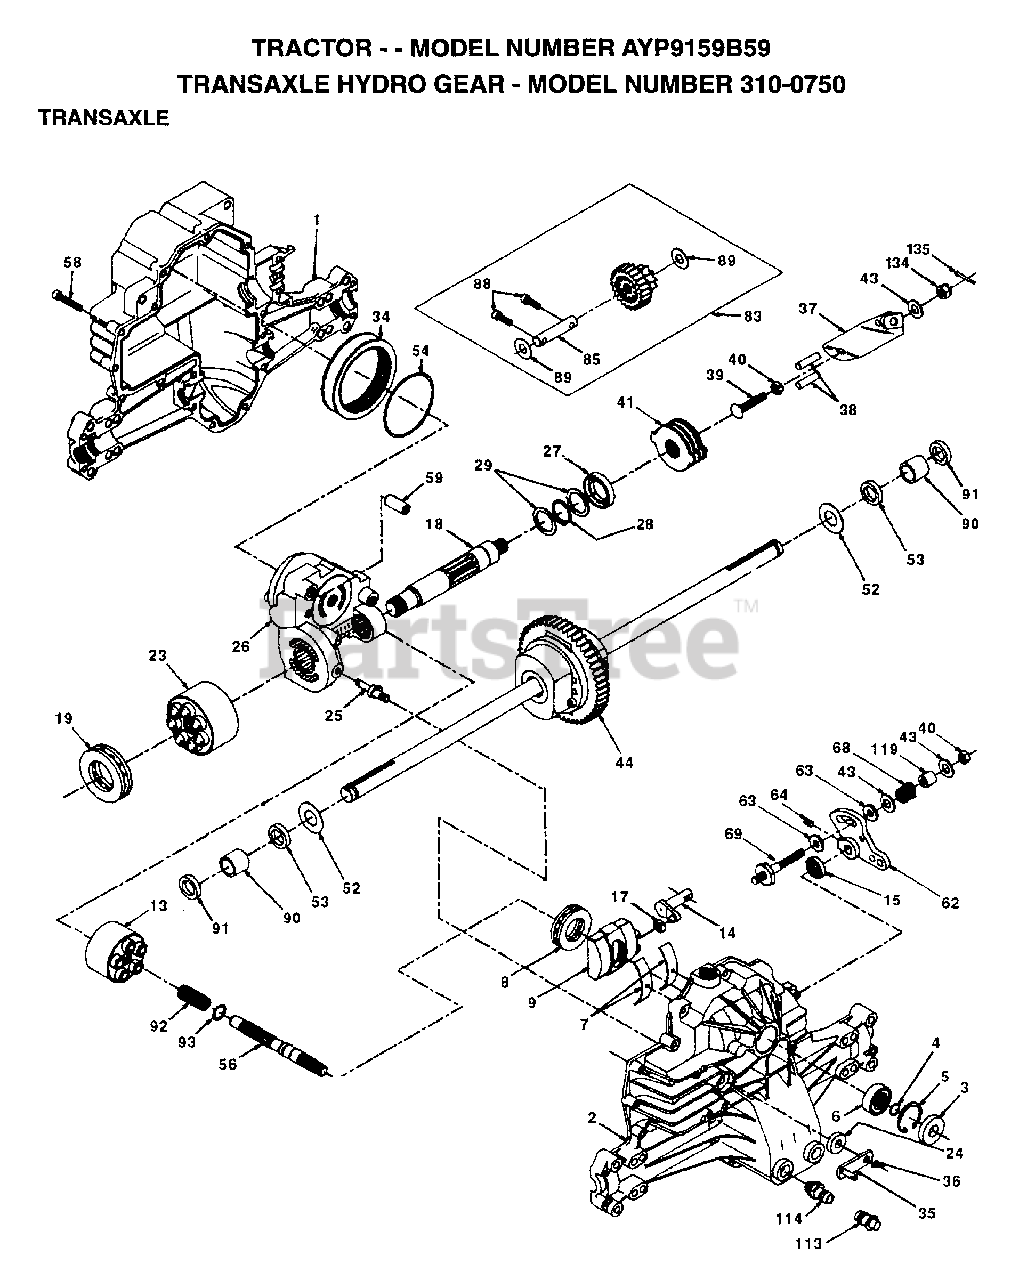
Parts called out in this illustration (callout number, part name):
1	HOUSING.L.50074RM
2	HOUSING.UP.70125
3	SEAL.9008000-0128
4	RING.RET.2003016.
5	RING.RET.2003052.
6	BEARING.(50552)42X68X16
7	CRADLE- 2003023.
8	BEARING.2003044.
9	SWASHPLT.2003087.
13	BLOCK.CLYN.70079.
14	ARM.TRUN.2003005.
15	SEAL.9008000-0126
17	GUIDE.2000015.
18	SHAFT.MOTOR.50115
19	BEARING.THS.50019
23	BLOCK.CYLIN.70082
24	SEAL.LIP.45074
25	ACTUATOR.2003555
26	KIT.CENTER.70133
27	SEAL.LIP.45075
28	RING RETAIN 50007
29	WASHER.44872
34	ELEMENT.OIL.44964
35	ARM.BYPASS.50270
36	RING.RETAIN.44870
37	ARM.ACTUAT.23710
38	PIN.ACTUAT.44891
40	NUT.LOCK.HX.50108
41	KIT.BRAKE.70135
43	WASHER HYD 44130
44	DIFFERENTIA.70130
52	WASHER.HYD.50152
53	SEAL.HYDRO.45076
54	O RING.HYD.45077
56	SHAFT.INPUT.50005
58	BOLT.1/4-20.44876
59	PIN.HYDRO.50002
62	ARM.CONTROL.50254
63	PUCK.DAMPER.50281
64	SCREW.SET.50018.
68	SPRING.HYD.50277
69	STUD.5/16-24.DANA
83	JACKSHAFT/PINION GEAR.70132
85	JACKSHAFT.50086
88	SCREW.CAP.50154.
89	WASHER.HYD.50132
90	BEARING.SLV.50118
91	SEAL.WIPER.50941
92	SPRING.2003014.
93	WASHER.2003017
113	CAP.VENT.70109
114	O-RING.ASM.70110
119	SPACER.HYD.50278
134	NUT.CAS.HYD.44142
135	PIN.COT.HYD.44101
